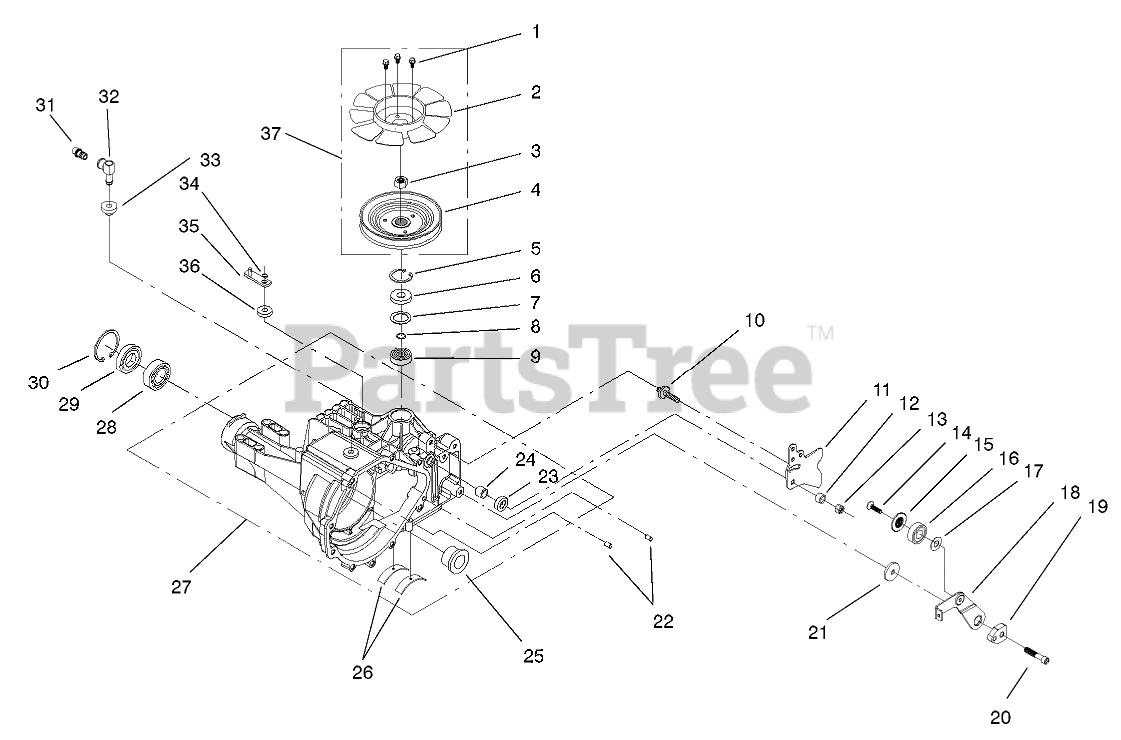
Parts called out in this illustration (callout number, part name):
3	NUT-HEX
4	PULLEY
5	RING-RETAINING
6	SEAL-LIP
7	SPACER
8	RING-WIRE, RETAINING
9	BEARING-SHAFT, BALL
11	ARM-CONTROL
12	SPACER-TRUNNION
13	NUT-HEX, LOCK
14	SCREW-COUNTERSUNK
15	SPACER-LOCATING
16	BEARING
17	WASHER
18	ARM-RETURN
19	PUCK-ADJUSTING
21	WASHER
23	SEAL-LIP
24	BUSHING-TRUNNION
25	BEARING-FLANGE
26	BEARING-CRADLE
27	MAIN HOUSING ASM
28	BEARING-BALL
30	RING-RETAINING
31	VENT CAP ASM
32	FITTING
33	BUSHING-RUBBER
34	RING-RETAINING
35	ARM-BYPASS
36	SEAL-LIP
37	FAN/PULLEY KIT
